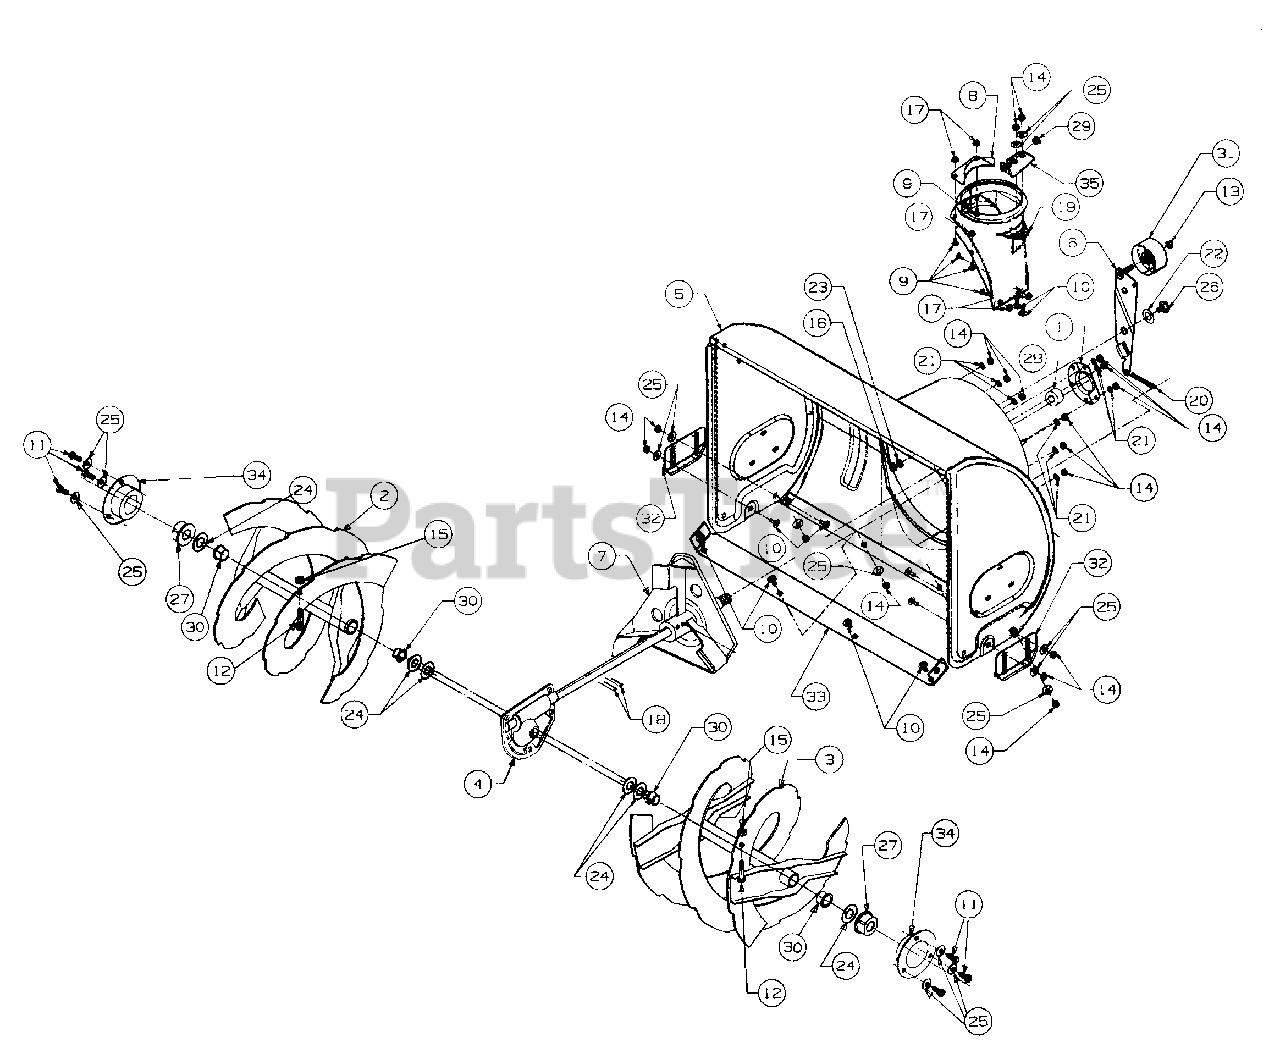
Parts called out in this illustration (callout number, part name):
1	Housing, Bearing
4	Gear Assembly (724TE)
9	Screw, Carriage, 1/4-20 x .50
10	Screw, Carriage, 5/16-18 x .75
11	Screw, Hex Wash Hd Tapp 5/16-18 x .62
12	Bolt, Shear, 5/16-18 x 1.5 (2 Spares)
13	Nut, Hex Insert Lock, 3/8-24
14	Nut, Hex, 5/16-18
15	Nut, Hex Insert Lock, 5/16-18 (2 Spares)
16	Nut, Hex 3/8-16
17	Nut, Hex Flange Lock, 1/4-20
18	Spring Pin, Spiral .25 x 1.5
19	Adapter, Chute
20	Spring, Extension
21	Lock Washer, 5/16
22	Washer, Flat, .65 x 1.25 x .02
23	Washer, Lock, 3/8
24	Washer, Flat, .76 x 1.49 x .06
25	Washer, Bell, .345 x .88 x .06
26	Screw, Shoulder
27	Bearing, Flange, .75 ID
28	Bearing, Ball, .75 ID
29	Bushing, Plastic, .380 ID
30	Bushing, Flange, .80 ID x .91 OD
31	Idler, Flat
